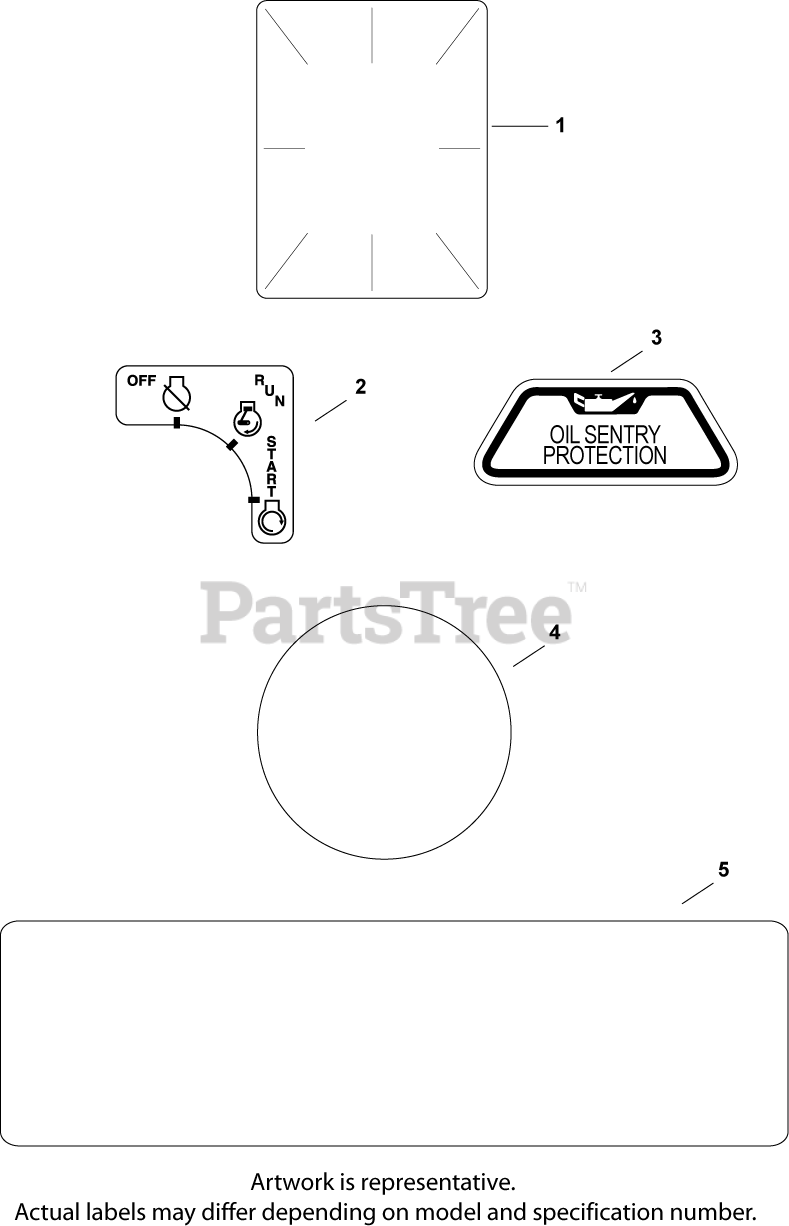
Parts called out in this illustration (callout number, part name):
1	DECAL, CLEAR LAMINATE USE 25 113 70-S
2	DECAL, KEY SWITCH
3	DECAL, OIL SENTRY - (#DSC)
4	LABEL, (ROUND KOHLER GOLD)-USE 24 113 18
5	DECAL, 25 HP
